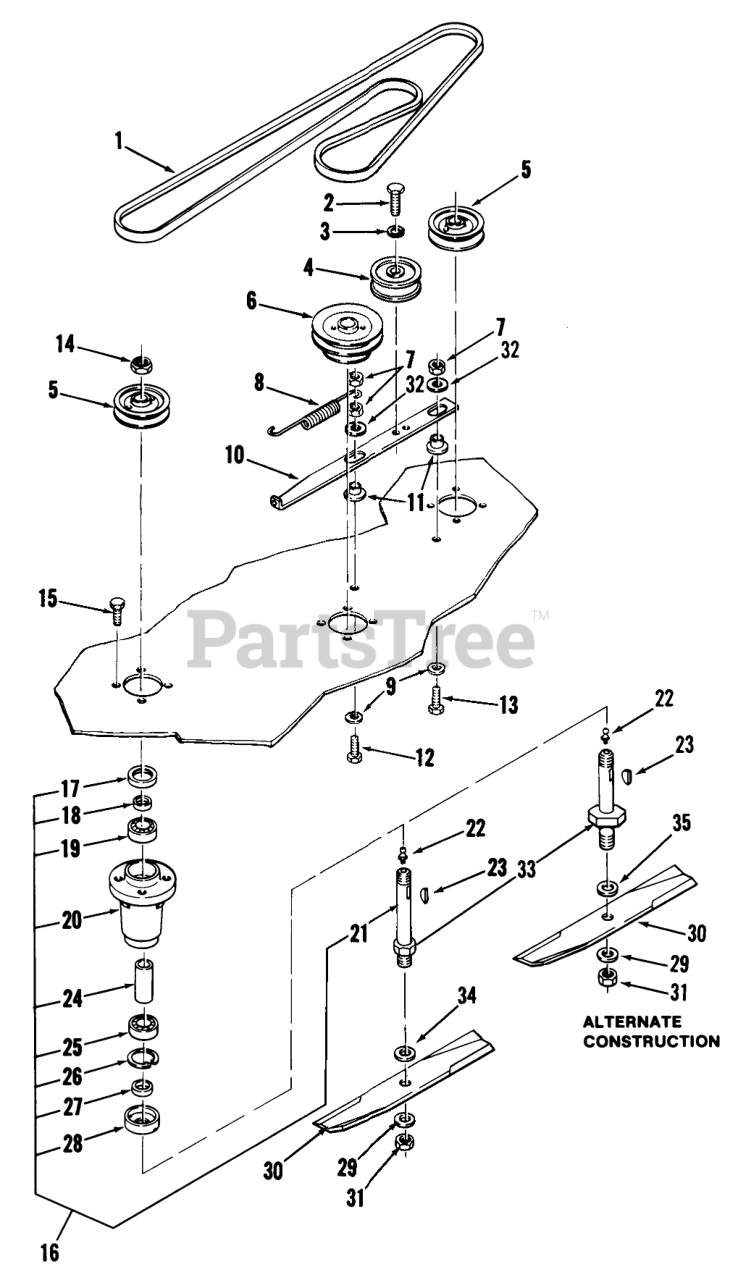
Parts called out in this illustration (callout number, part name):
1	V BELT
1	V-BELT
2	BOLT HEX SPECIAL
3	LOCKWASHER
4	Idler Pulley
5	PULLEY-BLADE DRIVE
6	PULLEY-42 MOWER SPDL
6	PULLEY-48 MOWER SPDL
7	NUT
8	SPRING-EXTENSION
9	WASHER
10	BAR-IDLER SUPPORT
11	SPACER-BUSHING
12	Bolt
13	Bolt
14	Nut
15	Bolt
16	Spindle Assembly
18	SPACER-SEAL
19	BEARING-BALL
20	HOUSING-SPINDLE
21	7" X 3/4" SHAFT.JAK
22	Grease Fitting
23	Hi-Pro Key 3/16 x 5/8
24	SPACER
25	BEARING-BALL
26	Ring-Snap
27	SPACER-BLADE
28	CUP-SPINDLE
29	SpeciaI Washer
30	14IN BLADE KIT
30	BLADE KIT (3 PACK)
31	Nut
32	WASHER
33	Spindle Shaft
34	Washer
35	SpeciaI Washer
